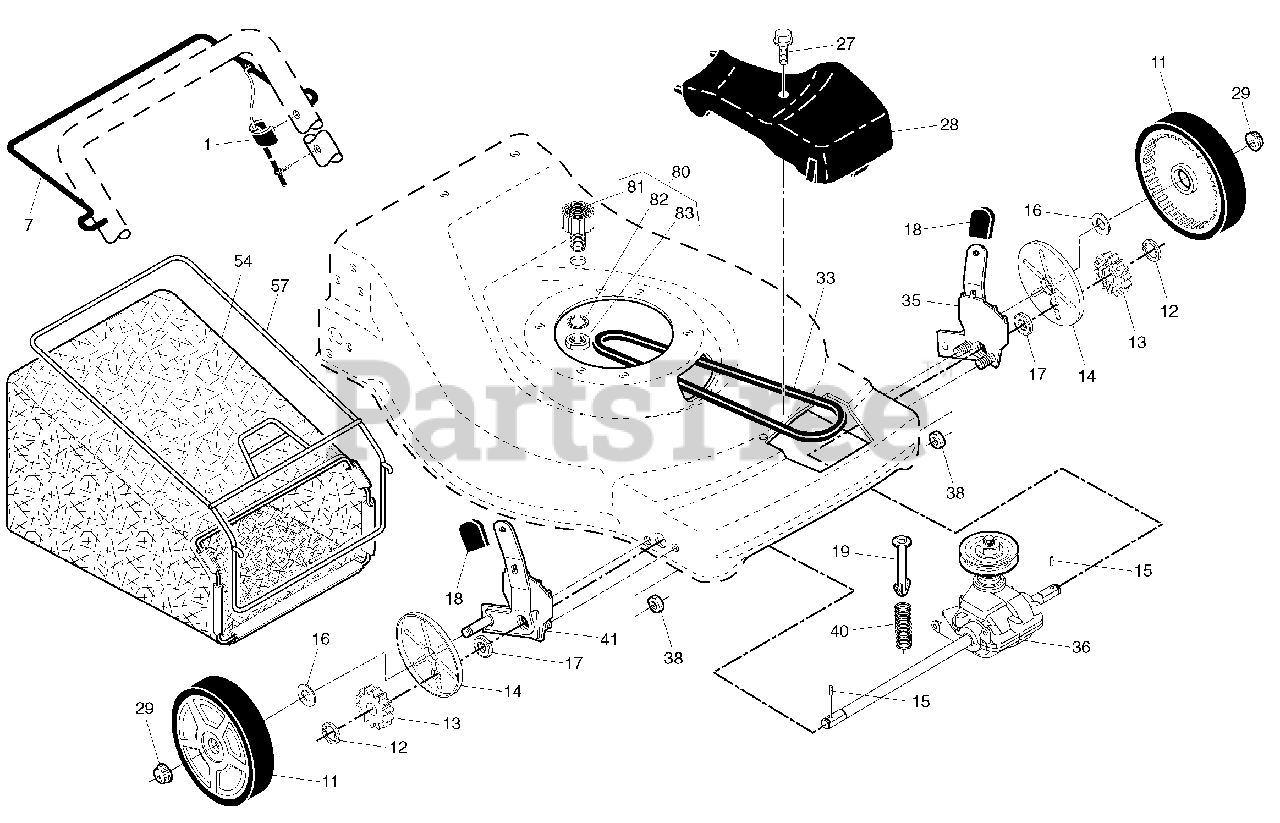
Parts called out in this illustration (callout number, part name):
1	Drive Control Cable
7	Bar, Drive Control
11	Wheel & Tire Assembly, Front
12	E-Ring
13	Pinion
14	Dust Cover
15	Pawl, Drive
16	Washer, Flat 3/8
17	Bearing, Wheel Adjuster Assembly
18	Selector Knob
19	Retainer, Spring
27	Pan Head Tapping Screw #10-24 x 2-3/4
28	Drive Cover
29	Locknut, Hex
35	Kit, Wheel Adjuster, LH
36	Gear Case Assembly, Complete
38	Locknut 1/4-20
40	Spring
41	Kit, Wheel Adjuster, RH
54	Grassbag Assembly
57	Frame, Grassbag
80	Water Washout Assembly
81	Fitting, Hose, Water Washout
82	Washer, Lock, Internal Tooth
83	Locknut, Hex, with O-Ring
